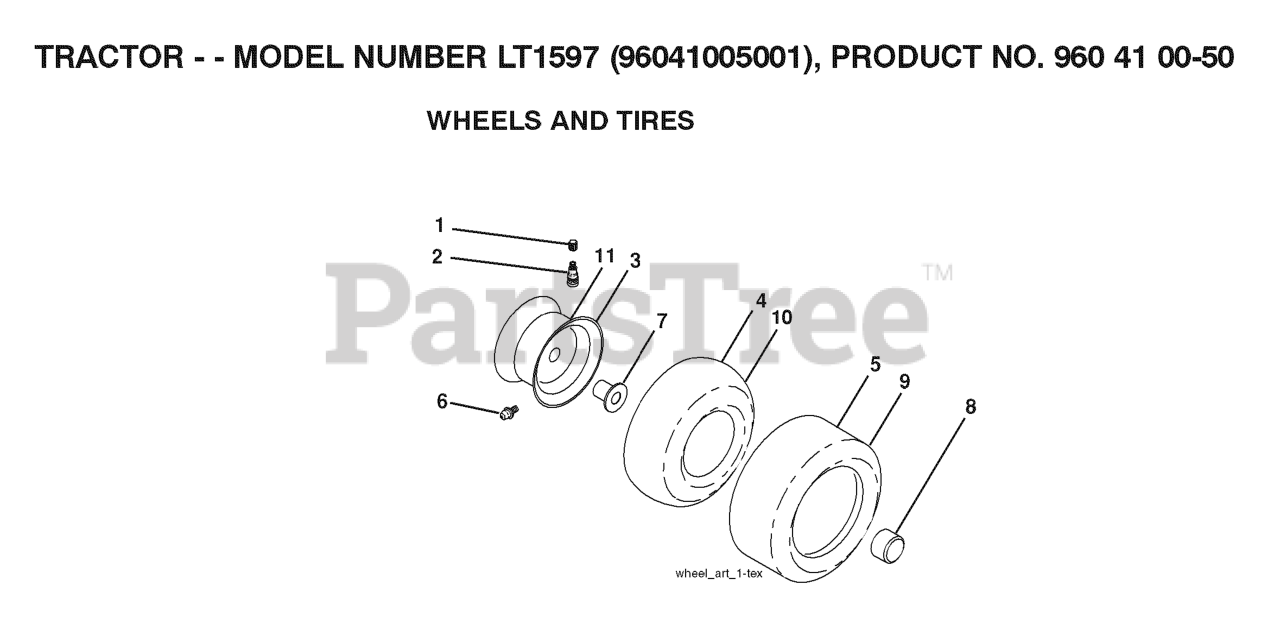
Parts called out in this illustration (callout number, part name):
1	GUARD.ENGINE.HUSQ.RZ.X498
2	FRAME.TUBE.RZ.MAIN.WELD.RH.ORG
3	FRAME.TUBE.RZ.MAIN.WELD.LH.ORG
4	TUBE.PNT.FRAME.RER.HUSQ.23".RZ
5	PLATES
5	PLATE, FOOT W/DECALS RZ
6	FRONT COVER RZ REFRESH
7	FOOTREST.PLATE.SUPPORT.X431
8	GROMMET.BUMPER
9	CROSS.PNT.MEMBER.BLK
10	SKID.PLATE.PNT.RZ.REF.SIVER
11	COVER.RAIL.RH.RZ.X668
12	COVER.RAIL.LH.RZ.X668
13	KNOB W/STUD
14	BUSHING SPHERICAL SUSP. FRONT
15	LINK, FRONT SUSP.
16	FENDER.SUPPORT.PNT.X431
17	SUPPORT.PNT.RH.CONSOLE.FRONT
18	SUPPORT.PNT.LH.CONSOLE.FRONT
19	BRKT ROD.BYPASS.EZT.X431
20	BOLT.FIN HEX 5/16-18UNC X2 1/4
21	BOLT HEX 5/16-18 GR 5
22	BOLT.HEX.FIN.3/8-16 X 3.GR5
23	BOLT.CARRIAGE.5/16-18.7/16
24	HHFS 3/8-16 X 3 GRD 5 ZD
25	BOLT SHOULDER,FLANGED,3/8-16X3
26	BOLT.5/16-18.THRD.ROLL.SHOULDR
27	BOLT.5/16HEX.WHS.HD
28	SCREW.#10 X 0.750.BOS
29	NUT ACORN,FLANGED,5/16-18
30	NUT LOCK HEX FLANGE 5/16-18
31	5/16-18 NYLOC FLANGE NUT
32	NUT 3/8-16 HEX FLG NYLOC ZD
33	7/16-14 HEX NUT W/NYL RING ZD
34	WASHER
35	WASHER 5/16"
